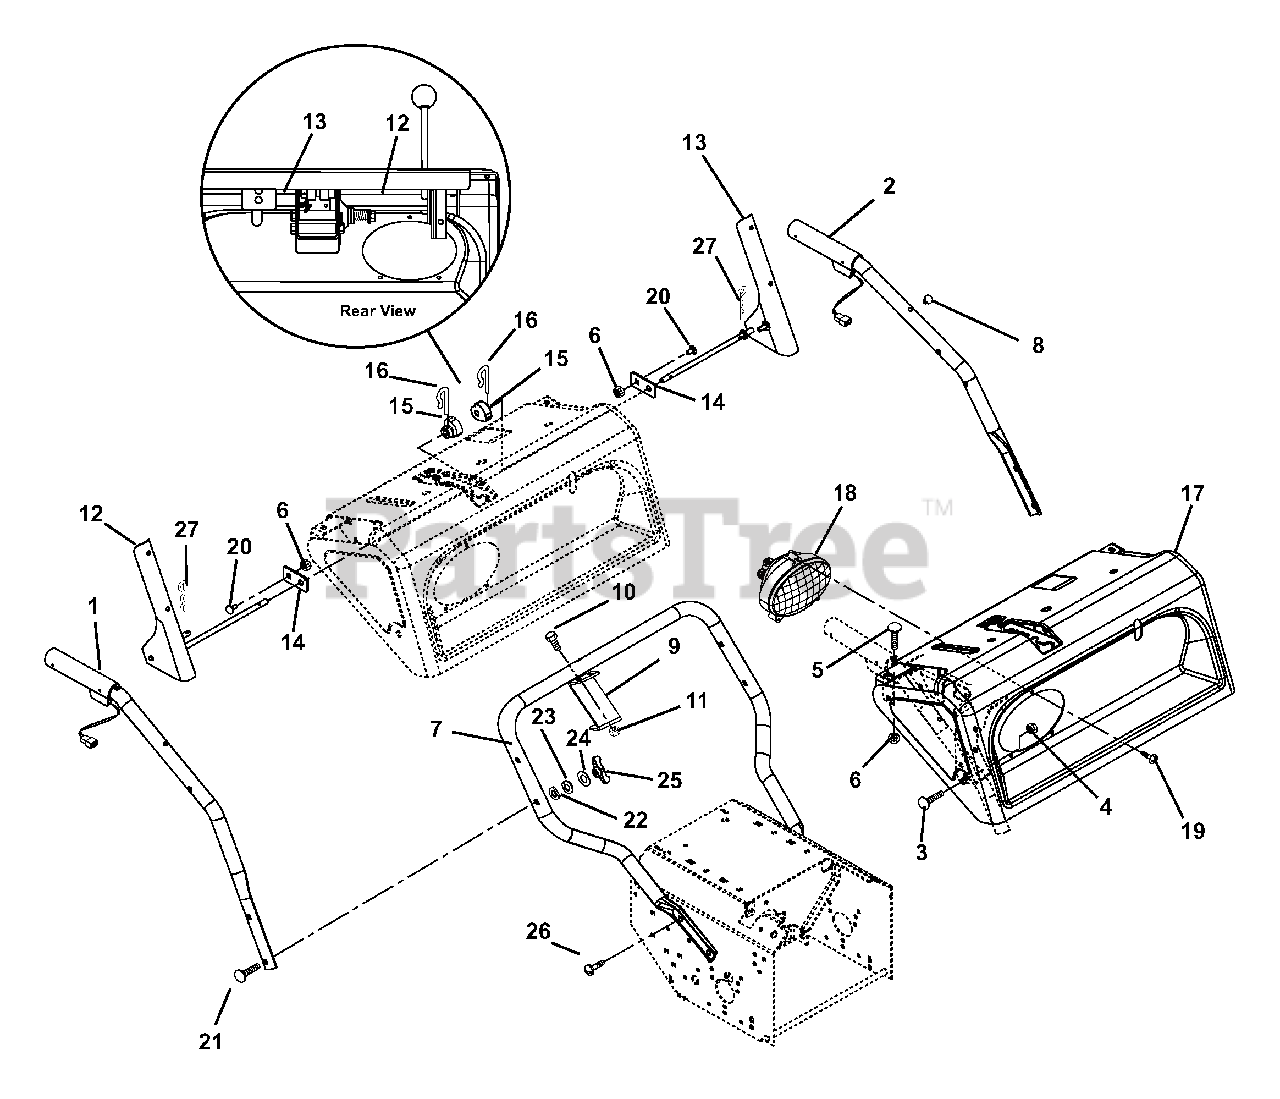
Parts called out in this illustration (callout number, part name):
1	HANDLEBAR, UPPER RH
2	HANDLEBAR, UPPER LH
3	@BLT-RDHDSQNK .31-18X1.75 G5YZ
4	@NUT-LK-CTR .31-18 YWZC
5	BLT-RDHDXLSQNK.25-20X1.25 G5ZC
6	@NUT-LK-CTR .25-20 YWZC
7	HANDLEBAR, LOWER
9	BRACKET, CHUTE CABLE
10	@BLT-HEX .25-20X1.50 GR5 YWZC
11	@NUT-LK-CTR .25-20 YWZC
12	KIT, RH LEVER W/GRIP
13	KIT, LH LEVER W/GRIP
14	BRACKET, RETAINING
15	CAM, INTERLOCK
16	PIN, SPRING CLIP
17	PANEL, W/CONTROL DECAL
18	HEADLAMP, OVAL W/ 1156 BULB
19	SCR-TAP 10-16X.75 HI-LO PPH
20	@BLT-RDHDSQNK .25-20X.50 G5YZ
21	@BLT-RDHDSQNK .31-18X2.25 G5YZ
22	WASHER,SADDLE-.320 X.937 X.062
23	WSHR-LK .312X.097 HVY YWZC
24	@WSHR-FL-STL.38X.875X.083 YWZC
25	KNOB - WING .312-18 UNC
26	BLT-SERHFWH .38-16X.75 YWZC
27	PIN-HAIR, ENDRIES #25 YWZC
